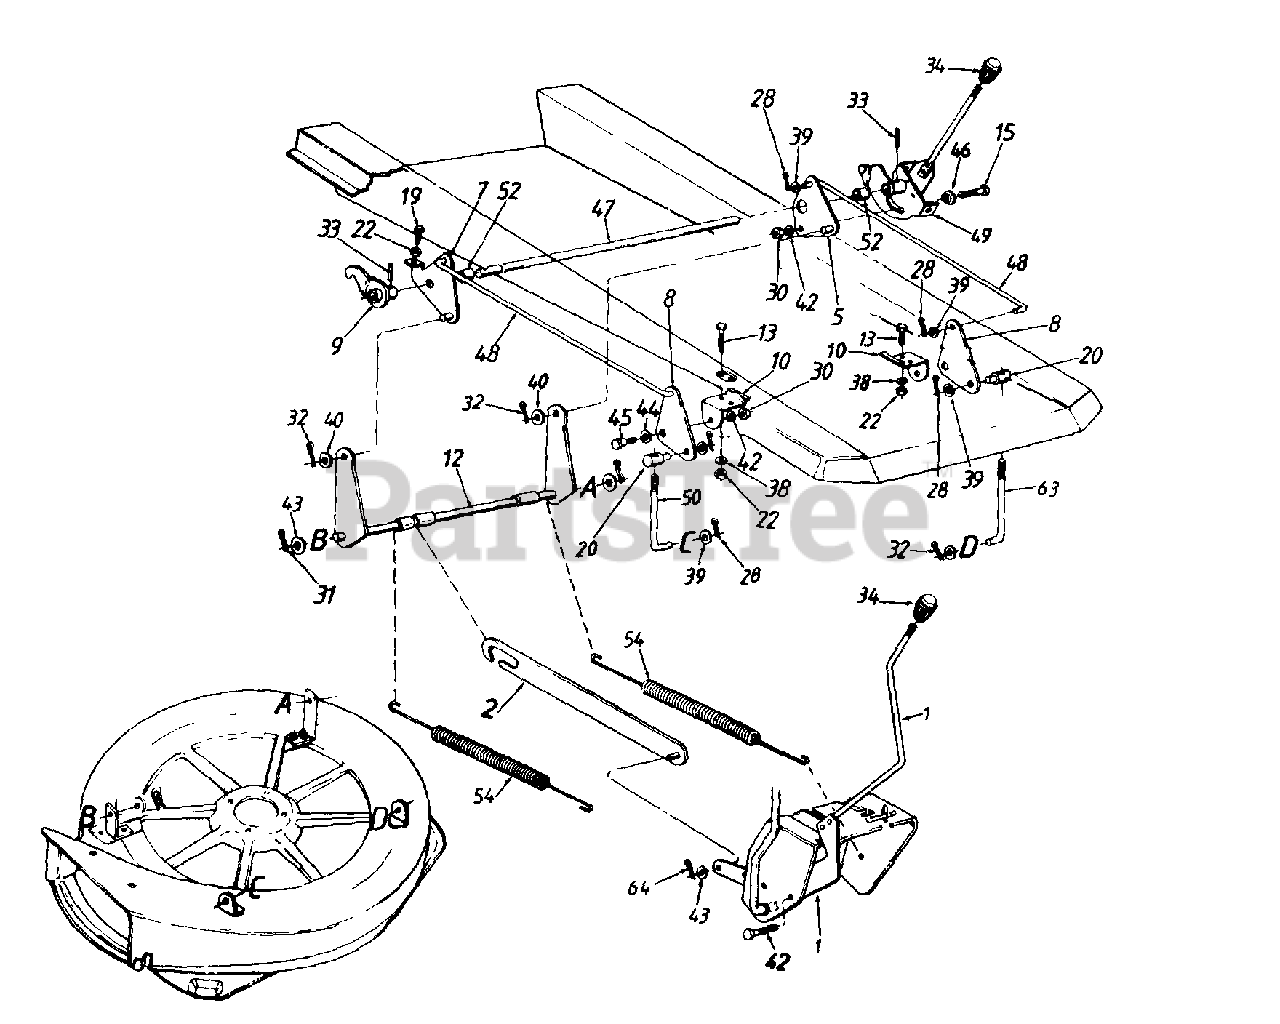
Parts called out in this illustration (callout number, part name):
7	Deck Lift Brkt. Ass'y.
8	Deck Lift Bracket
9	Deck Lift Float Brkt Ass'y.
10	Deck Lift Pivot Brkt.
15	Hex Bolt 3/8-16 x 1" Lg.
19	Hex Wash.-Tap Scr. 5/16-18 x 1.25" Lg.
20	Ferrule
22	Hex Nut 5/16-18 Thd.
28	Cotter Pin 3/32" Dia.
30	Hex Nut 3/8-16 Thd.
31	Internal Cot. Pin 1/2" Dia.
32	Int. Cot. Pins 3/8" Dia.
33	Spring Pin Spir, 1/4" Dia.
34	Knob
38	L-Wash 5/16" 1.0.
39	FI-Wash. 385 I.D. x.62
40	Fl-Wash. 635 I.D. x 1.12
42	L-Wash. 3/8" I.D.
43	FI-Wash..385 I.D. x .87 O.D.
44	Spring Washer.530 I.D.
45	Shld. Bolt .500" Dia. x .215"
46	Shld. Spacer 625" I.D.
47	Rear Hgt. Adj. Shaft
50	J-Bolt 3/8-24 x 5.25" Lg.
52	Spacer .885 l.D.
54	Ext. Spring 13.25" Lg.
63	J-Bolt 3/8-24 x 5.4" Lg.
64	Cotter Pin 1/8" Dia
